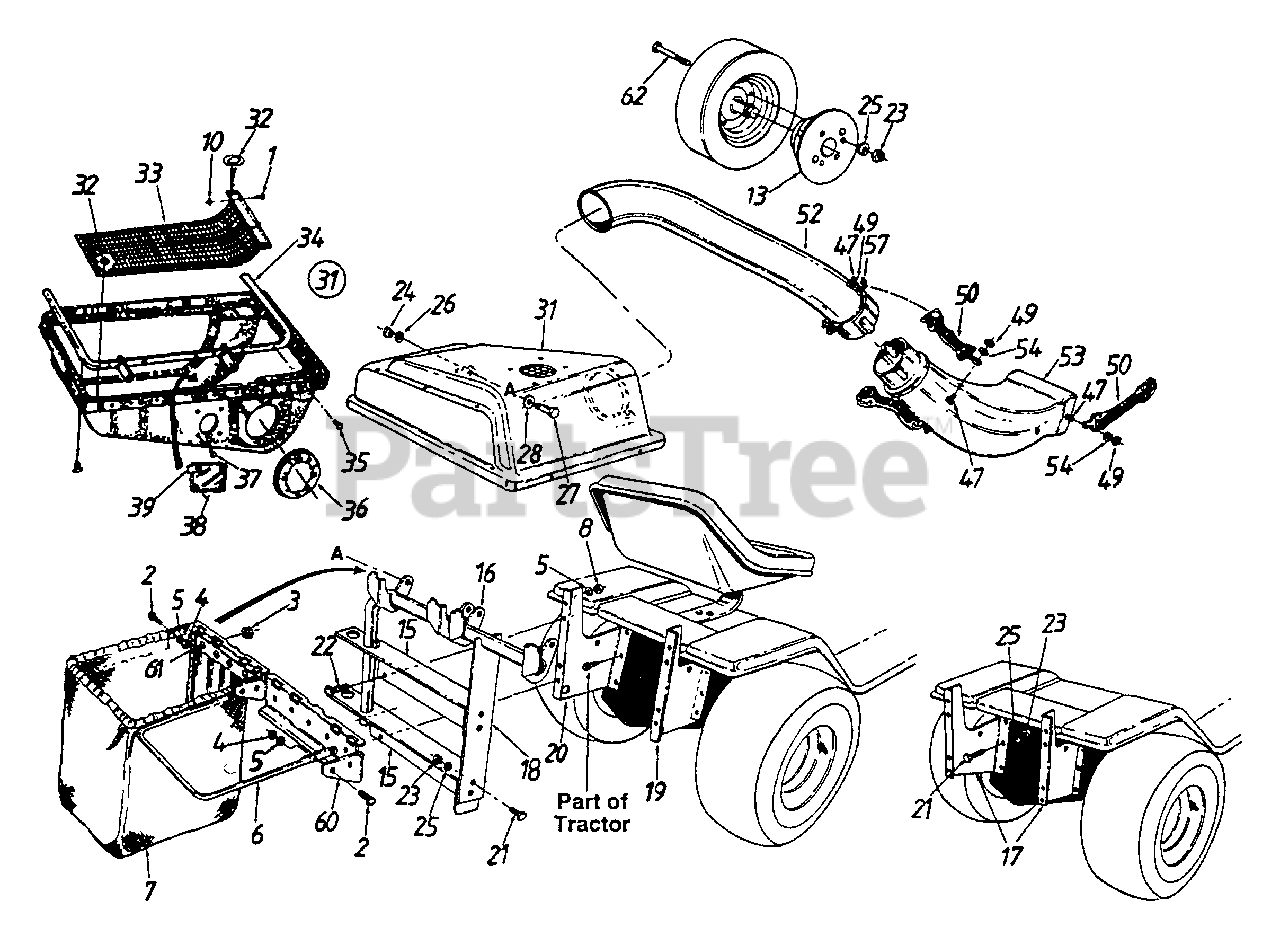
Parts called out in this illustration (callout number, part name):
1	Pop Rivet .188 Dia.
2	Hex Bolt 1/4-28 x .88"
3	Hex Sems Nut #10-24 Thd.
4	Hex Nut 1/4-28 Thd.
5	L-Wash. 1/4" I.D.
7	Grass Catcher Bag
8	Hex Nut 1/4-20 Thd.
10	Flat Wash. 1/4" I.D.
22	Hex Bolt 1/4-20 x .62" Lg.-Gr. 5
23	Hex Nut 5/16-18 Thd.
24	Hex Nut 3/8-16 Thd.
25	L-Wash. 5/16" I.D.
26	L-Wash. 3/8" I.D.
27	Shld. Bolt 3/8-16 x .50" Dia.
28	Bell-Wash. .505" I.D. x 1.0" O.D.
31	Grass Catcher Cover Ass'y.
32	Twist Fastener
35	Hex AB-Tap Scr. 1/4 x .62"
37	Truss B-Tap Scr. #10 x .5" Lg.
38	Plastic Plate
39	Speed Nut
47	Hex Bolt 1/4-20 x .625"
49	Hex Ins. L-Nut 1/4-20 Thd.
50	Retainer Strap Ass'y.
52	Catcher Tube
53	Discharge Tube
54	L-Wash. .27" I.D.
57	Retainer Hook Brkt.
61	Truss Mach. Scr. #10-24 x .5"
62	Hex Bolt 5/16-18 x .4" Lg.
